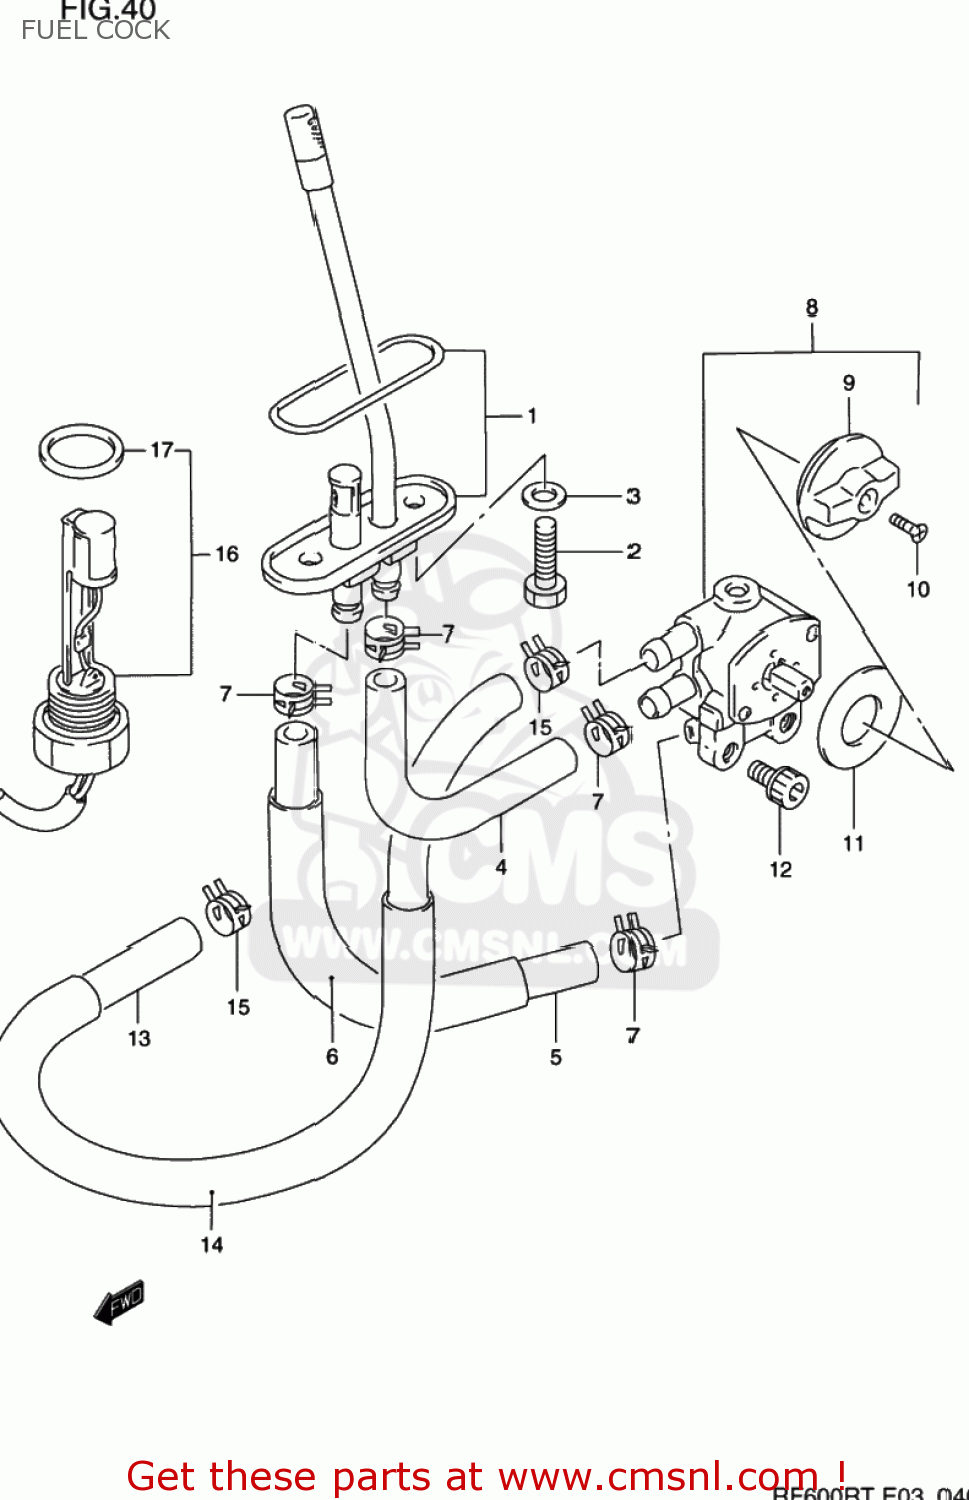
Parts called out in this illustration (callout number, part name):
1	FILTER,FUEL
2	BOLT(6X20)
3	GASKET(6.4X11.5X0.8) (NAS)
4	HOSE,FUEL ON
5	HOSE (7X12X600)
6	PROTECTOR(14.5X15.5X600)
7	CLIP
8	COCK ASSY,FUEL
9	LEVER,FUEL COCK
10	SCREW,COCK LEVER
11	COVER,FUEL COCK
12	SCREW 6X12
13	HOSE (7X12X600)
14	PROTECTOR(14.5X15.5X600)
15	CLIP
16	GAUGE ASSY,FUEL LEVEL
17	GASKET,FUEL LEVEL GAUGE (NAS)
